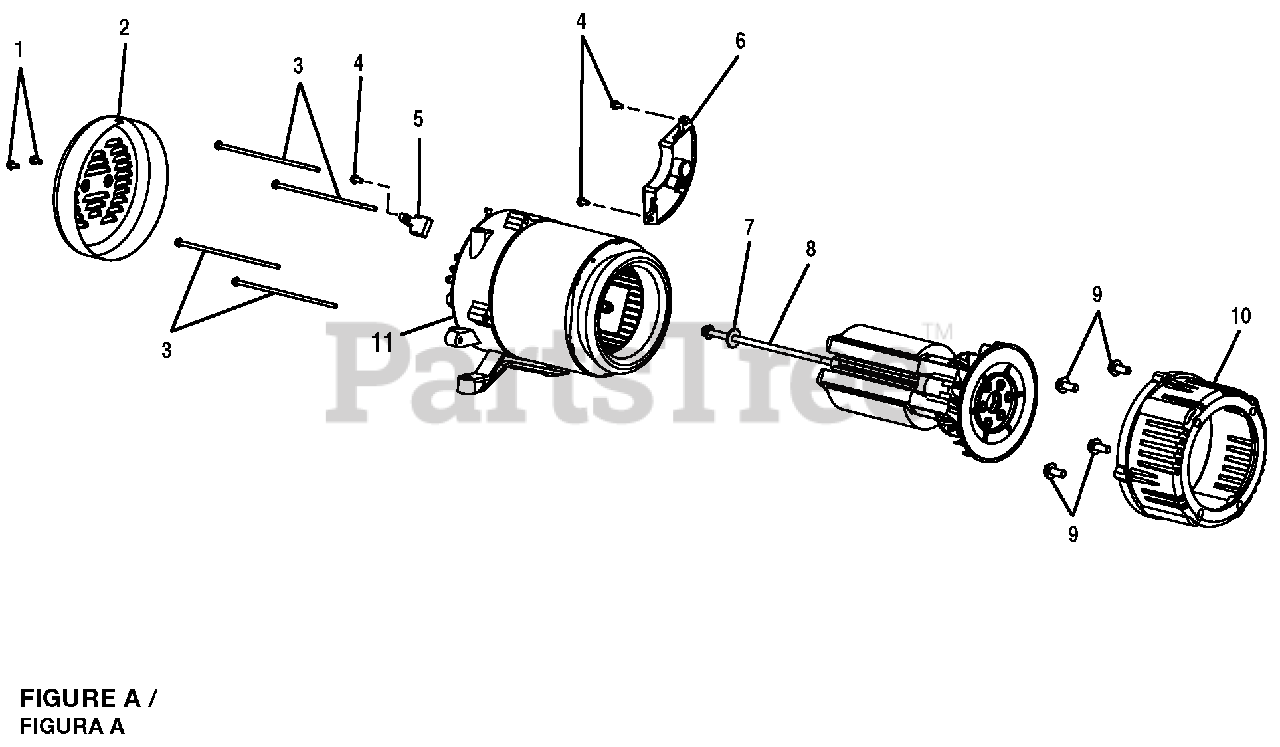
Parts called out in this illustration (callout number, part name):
2	Brush Cover
3	Bolt (M6 x 164 mm)
5	Brush Assembly
6	Automatic Voltage Regulator
7	Washer ( 5/16 in.)
8	Bolt (5/16-24 x 215 mm, Hex. Hd.)
9	Bolt (3/8-18 x 1-1/4 in.)
10	Engine Adapter
11	Bearing Support
